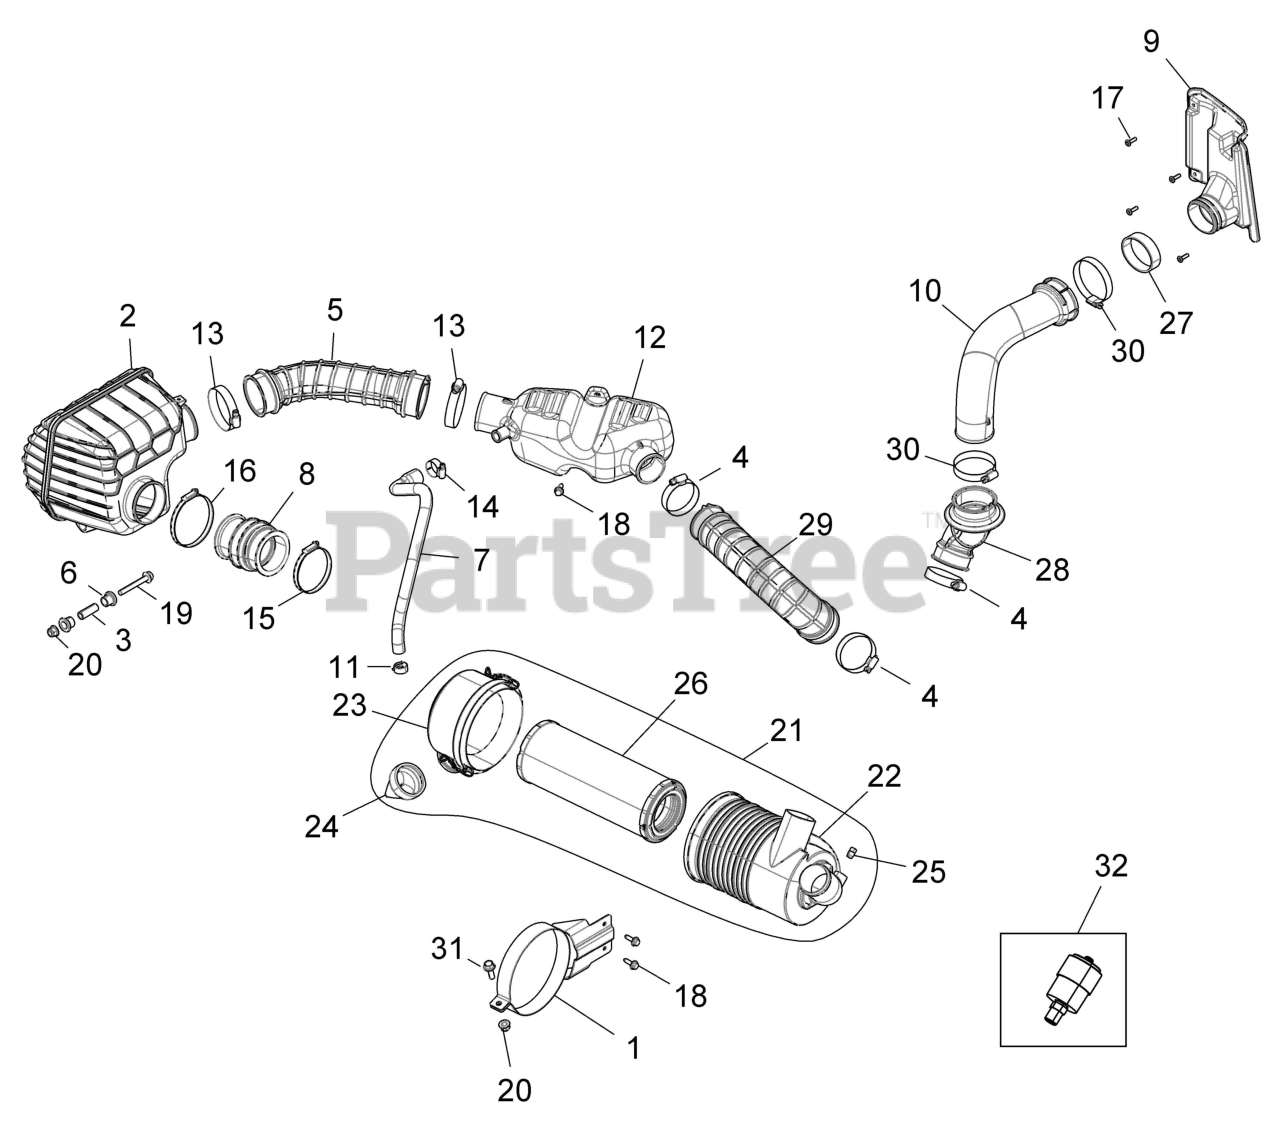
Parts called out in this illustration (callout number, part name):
1	WELD-AIRBOX,MOUNT
2	WELD-INTAKE,PLENUM
3	SHAFT-COMPRESSION LMTR,34.4MM
4	CLAMP, HOSE, S.S.(10)
5	HOSE, ENGINE INTAKE
6	BUSHING-MOUNT
7	ASM, ENGINE VENT
8	BOOT-THROTTLE BODY
9	INTAKE-FENDER,REAR,BLK
10	DUCT-INTAKE,AIR
11	CLAMP, HOSE, SPRING
12	DUCT-INTAKE,ENG
13	CLAMP-HOSE, 2.75"-SS
14	CLAMP,HOSE
15	CLAMP,BAND,NARROW (10)
16	CLAMP-BAND,NARROW 70-90MM
17	SCR-10X5/8-HI/LO,PN-T25,TRX-M
18	SCR-M6X1.0X20,HXHD,FLG,TDFM,BL
19	SCR-HXFL-M8X1.25X60 8.8 ZOD
20	NUT-M8X1.25,FLG,NYLOC-OLIVE D
21	ASM., AIR INTAKE
22	ASM., AIRBOX, MAIN
23	ASM-LID,AIRBOX
24	VALVE-AIRBOX
25	PLUG-AIRBOX
27	HOSE-INTAKE,BOOT
28	HOSE-INTAKE,AIR BOX,SPLY
29	HOSE-AIR BOX,SPLY
30	CLAMP, HOSE
31	BOLT-M8X1.25X25,HXFLG-OLIVE D
32	KIT, FILTER, INDICATOR
